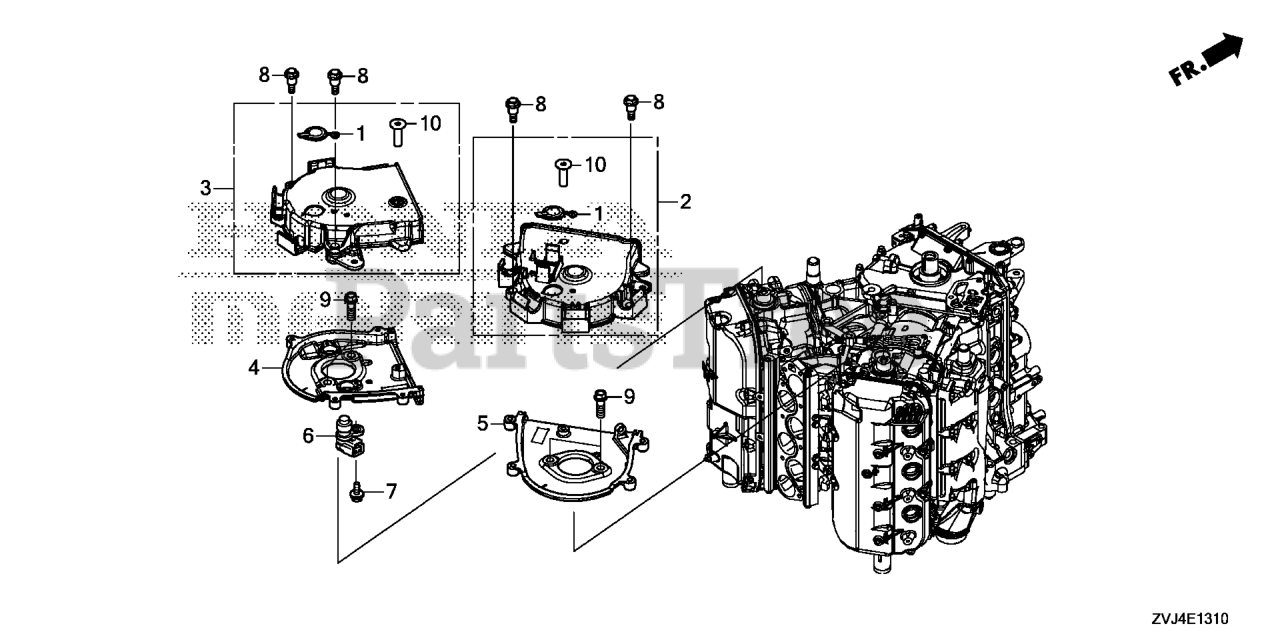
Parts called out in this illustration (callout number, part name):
1	GROMMET, TIMING BELT COVER
2	COVER ASSY., R. TIMING BELT
3	COVER ASSY., L. TIMING BELT
4	PLATE, L. TIMING BELT COVER
5	PLATE, R. TIMING BELT COVER
6	SENSOR ASSY., TDC
7	BOLT-WASHER (5X16)
8	BOLT, TIMING BELT COVER
8	BOLT, T/B COVER
9	BOLT, SPECIAL (8X29)
10	COLLAR, TIMING BELT COVER
